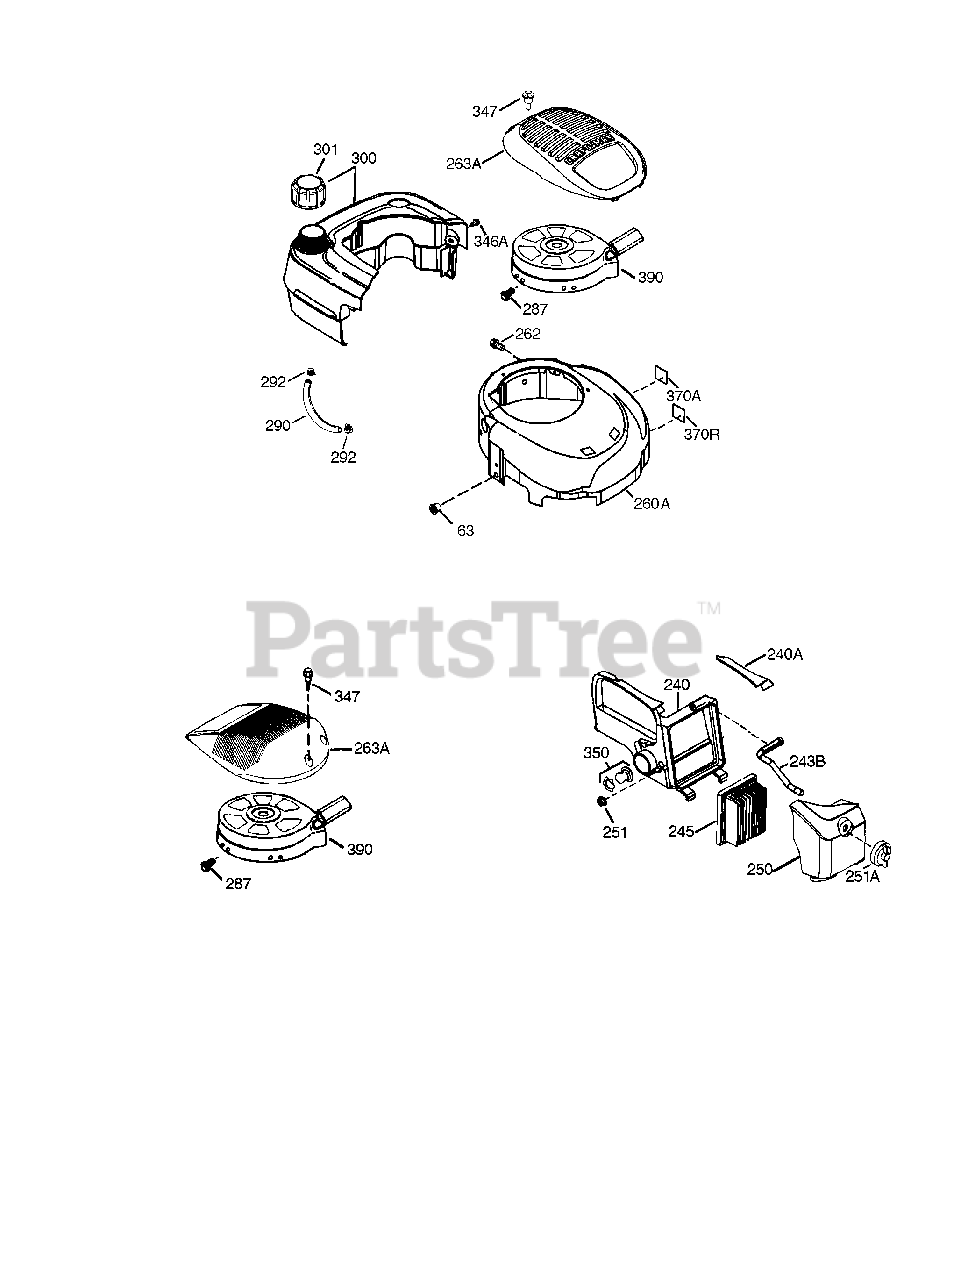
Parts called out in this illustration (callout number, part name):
206	Terminal Ass'y.
240	Air Cleaner Body (Incl.239,299 & 350)
245	Air Filter (Paper) (also available in Packaged Part #740031B for model VLV only) (also available in Packaged Pa rt #740061C for model OH195)
250	Air Cleaner Cover
251	Lock Nut, 1/4-20
262	Screw, 1/4-20 x 1-1/2"
287	Screw, 8-32 x 21/64"
290	Fuel Line
292	Fuel Line Clamp
300	Fuel Tank (Incl. 301)
301	Fuel Cap
346A	Screw, 10-32 x 35/64"
350	Primer Bulb (Red)
370A	Lubrication Decal
390	Rewind Starter (NOTE: This engine co uld have been built with 590738 start er).
999	Summer Maintenance Kit (incl. Oil, Sp ark Plug, Air Cleaner, & Ultra Fresh)
